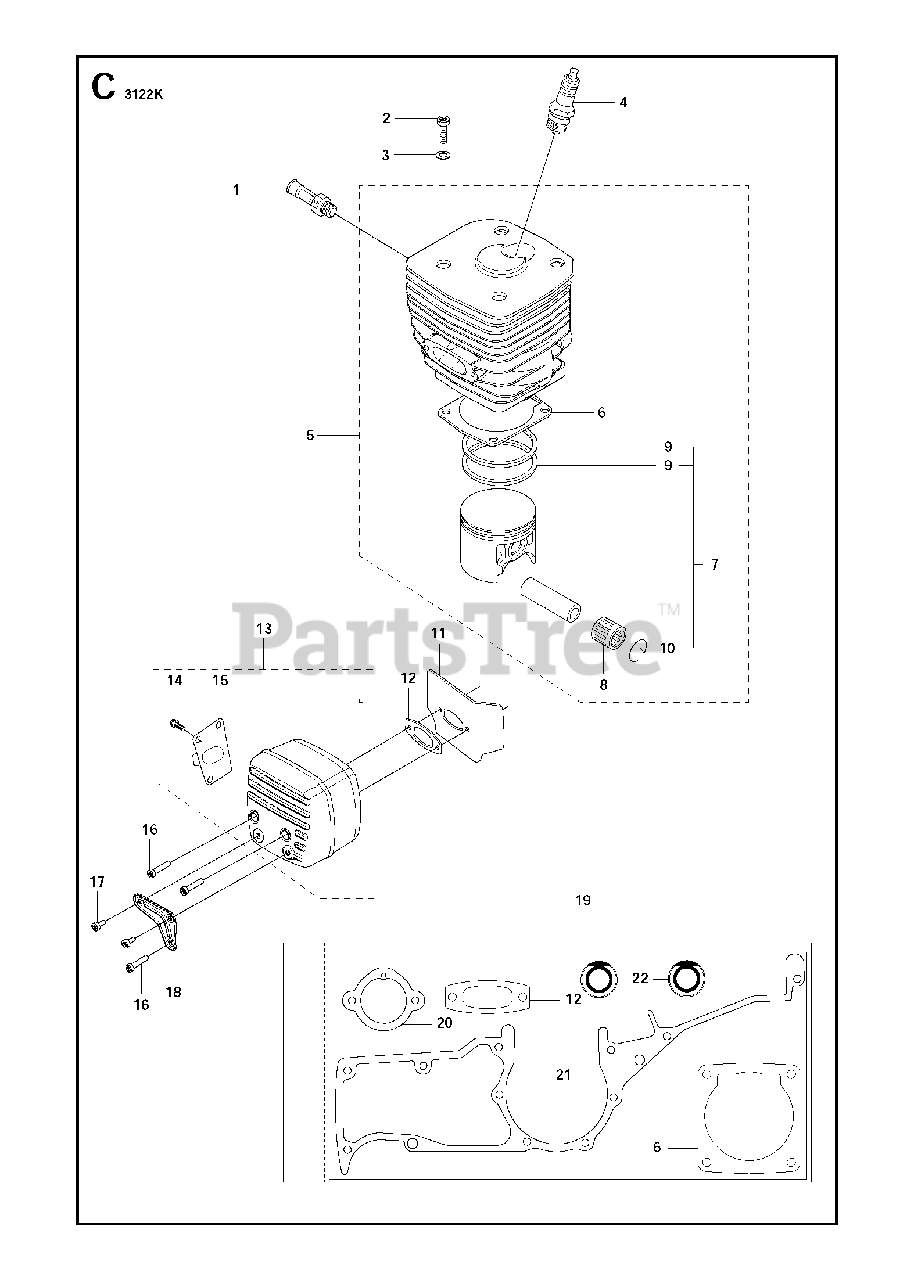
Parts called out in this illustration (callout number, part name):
1	DECOMPRESSION VALVE
5	CYLINDER ASSYIncl. 6 - 8
7	PISTON ASSYIncl. 9 - 10
8	NEEDLE HOLDER
11	COOLING AIR CONDUCTOR
13	MUFFLER ASSYIncl. 14 - 15
15	EXHAUST DUCT
16	SCREW ITXSCM
17	SCREW ITXSCM
19	GASKET KITIncl. 6, 12, 20 - 22
22	SEALING RING
